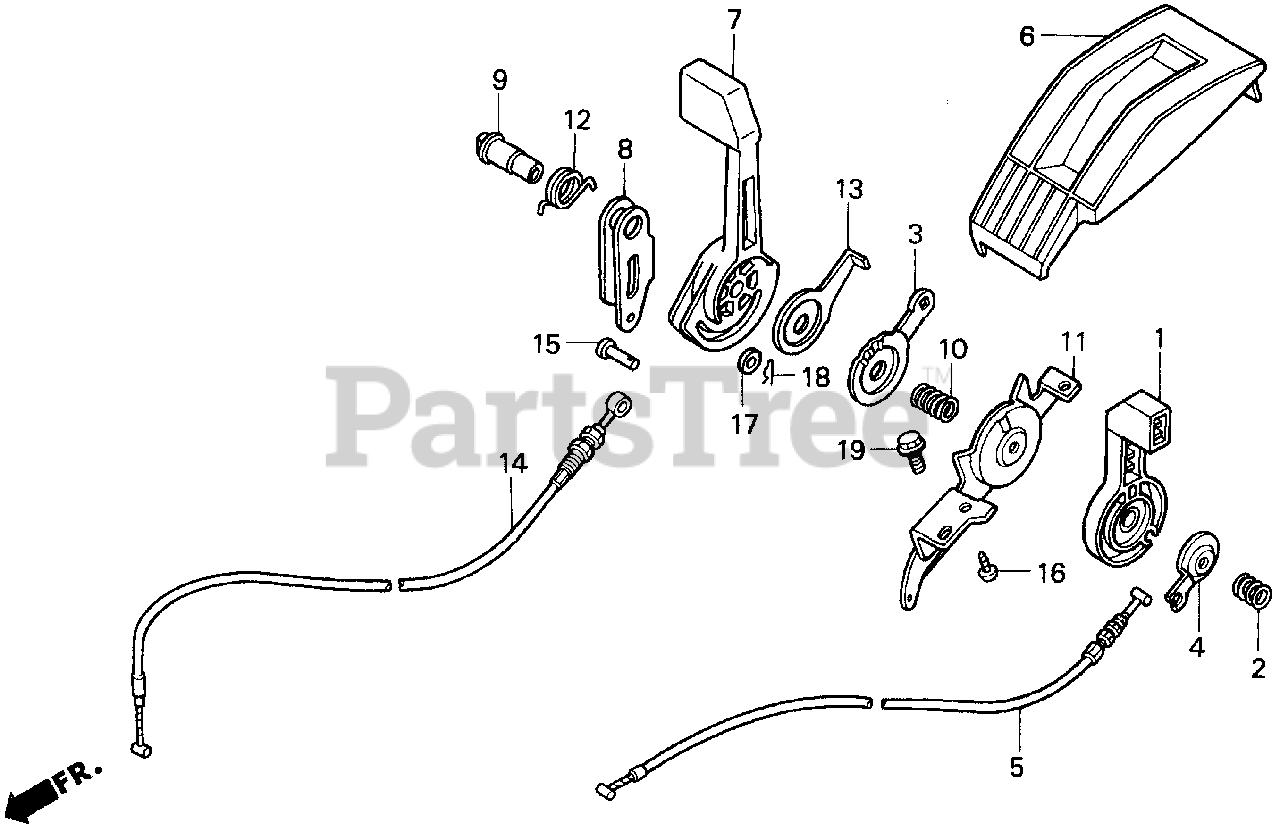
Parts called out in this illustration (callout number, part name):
1	LEVER, THROTTLE
2	SPRING, THROTTLE LEVER
3	SEAT, SPRING
4	SEAT, SPRING
5	CABLE, THROTTLE
6	COVER, CONTROL
7	LEVER, CHANGE
8	ARM, CHANGE LEVER
9	NUT, CHANGE LEVER
10	SPRING, CHANGE LEVER
11	PLATE, STOPPER
12	SPRING, ARM RETURN
13	PLATE, THRUST
14	CABLE, CHANGE (CAPRO)
15	PIN (6X22)
16	SCREW, TAPPING (5X12)
17	WASHER, PLAIN (6MM)
18	PIN, LOCK (6MM)
19	BOLT, FLANGE (6X10)
